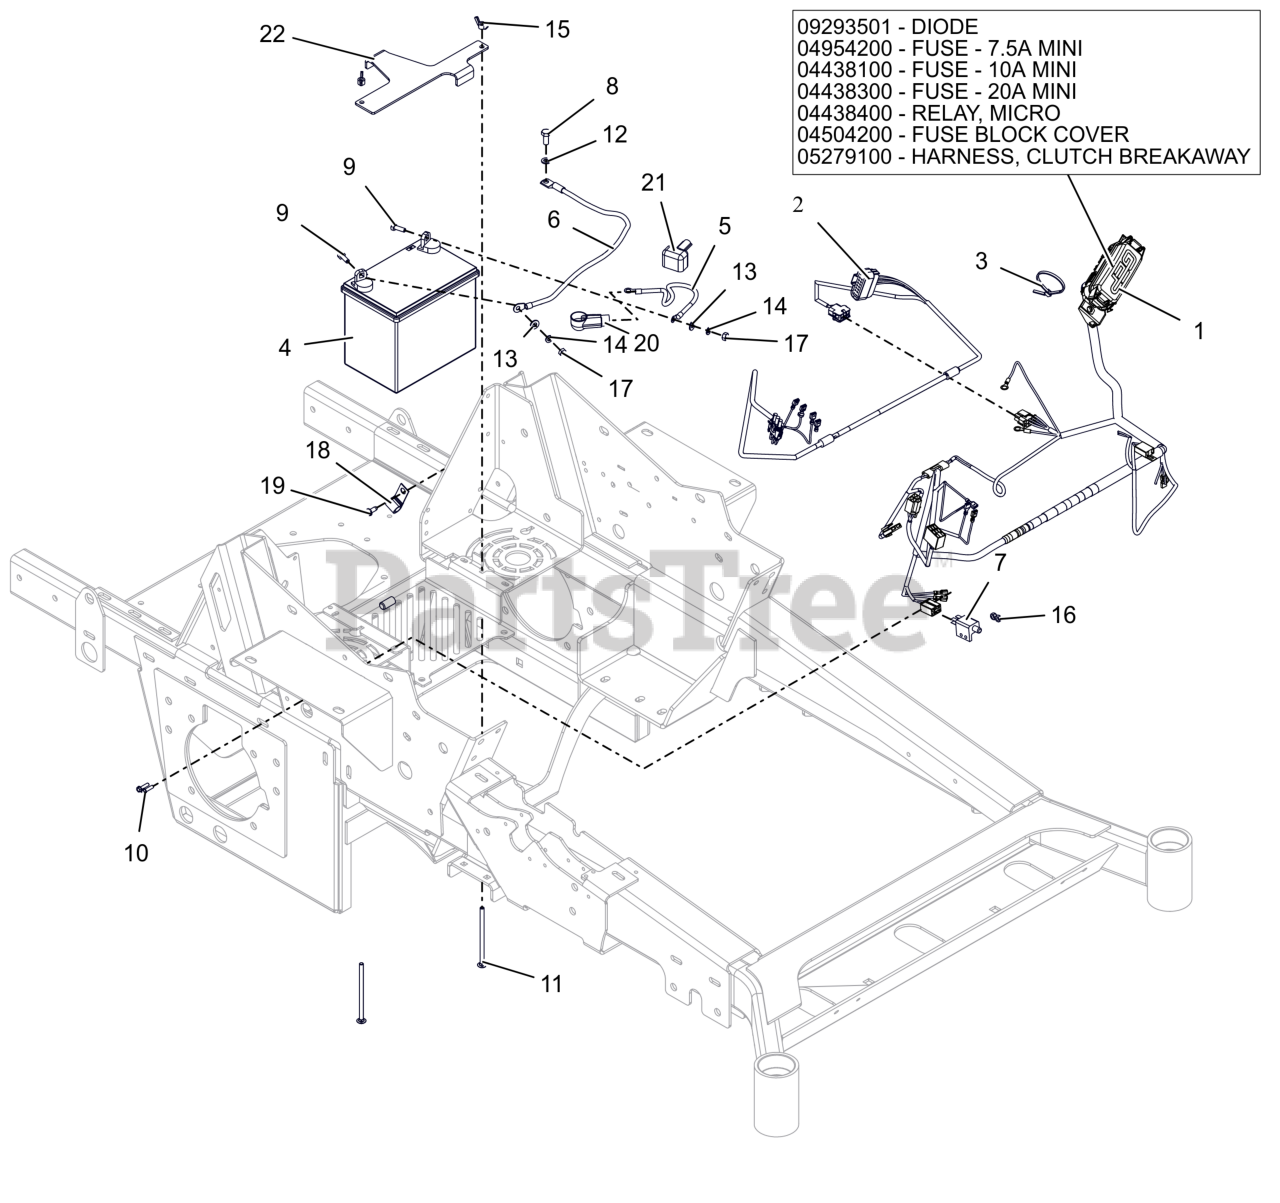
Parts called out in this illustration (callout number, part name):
1	HARNESS- WIRE PT300 MAIN
1	DIODE, CONNECTOR SHELL
1	FUSE, 7.5 AMP MINI-ATC
1	FUSE,10 AMP MINI-ATC
1	FUSE,20 AMP MINI ATC
1	RELAY,MICRO5 TERML W/RESISTOR
1	COVER, HARNESS FUSE/RELAY MOD
1	HARNESS, CLUTCH BREAKAWAY
2	HARNESS- EFI ENG ADAPTER PT300
3	CABLE TIE, .15 X 8.50
4	BATTERY, 300 CCA 10U1L
5	CABLE, STARTER 13.00"
6	CABLE- NEG 16.00 IN
7	SWITCH- DOUBLE POLE N.O./N.O.
8	BLT, HEX M8-1.25X20 G8.8 ZCC
9	BLT, HEX .25-20X.75 G5 ZCC
10	BLT, HWH #10-24X.75 ZCC
11	BLT, RHSN .25-20X4.50 G5 ZCC
12	WSHR,LK-REG .312X.078 ZCC
13	WSHR,FLT .281X.625X.065 ZCC
14	WSHR,LK-REG .250X.062 ZCC
15	NUT, LK-WING .25-20 ZCC
16	NUT-LK-NYL #10-24 G2 ZCC
17	NUT-STD .250-20 G2 ZCC
19	SCR,TAP .25-20X.625 HWH ZCC
20	BOOT, .65ID POS
21	INSULATOR
22	HOLDDOWN- BATTERY
